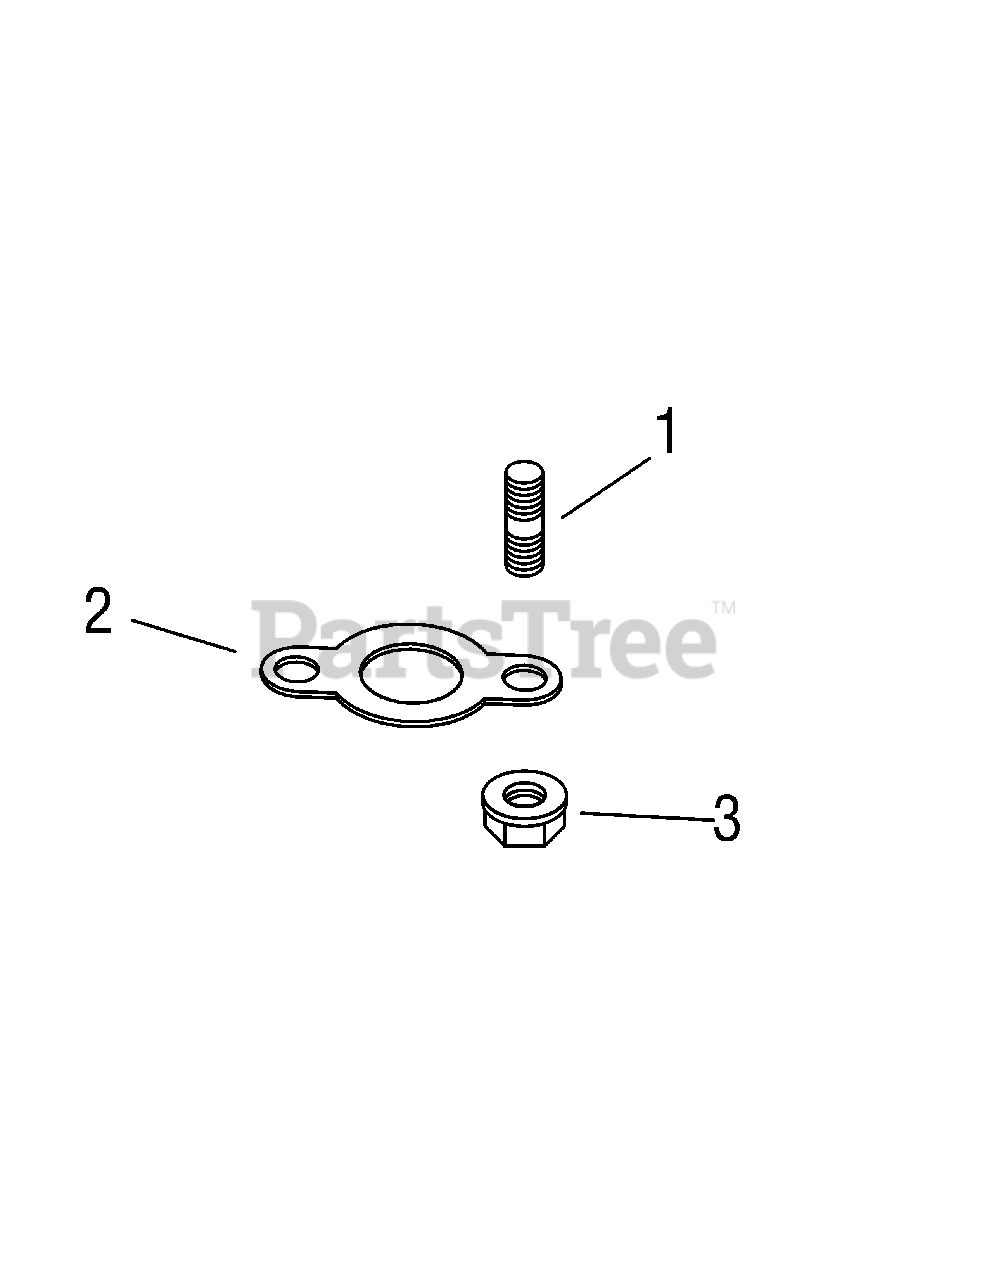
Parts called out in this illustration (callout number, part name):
1	Stud, M8x1.25x33
2	Gasket, exhaust manifold
3	Nut, hex. flange M8x1.25
